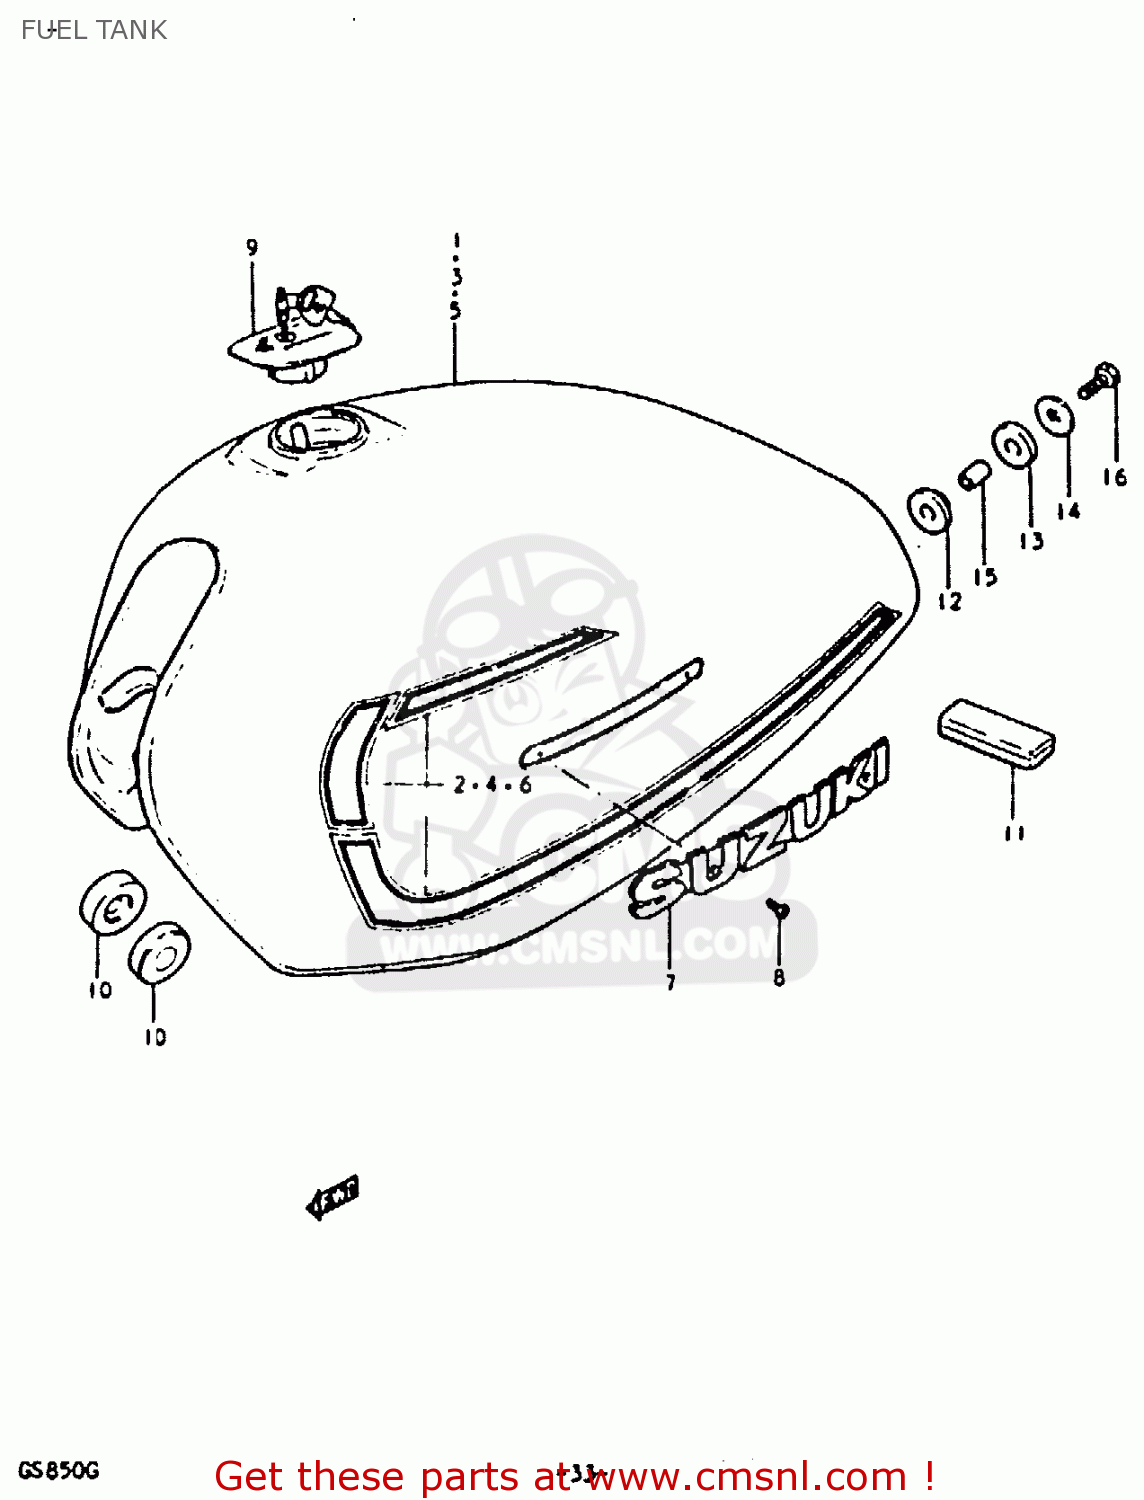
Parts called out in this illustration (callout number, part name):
1	TANK, FUEL
2	TAPE SET
3	TANK, FUEL
4	TAPE SET
5	TANK, FUEL
6	TAPE SET
7	EMBLEM,FUEL TANK
8	SCREW 3X6
9	CAP SET,FUEL TANK
10	CUSHION
11	CUSHION
12	CUSHION
13	CUSHION
14	WASHER (8.5X29X1.6)
15	SPACER(8.5X12X19)
16	BOLT (8X30)
